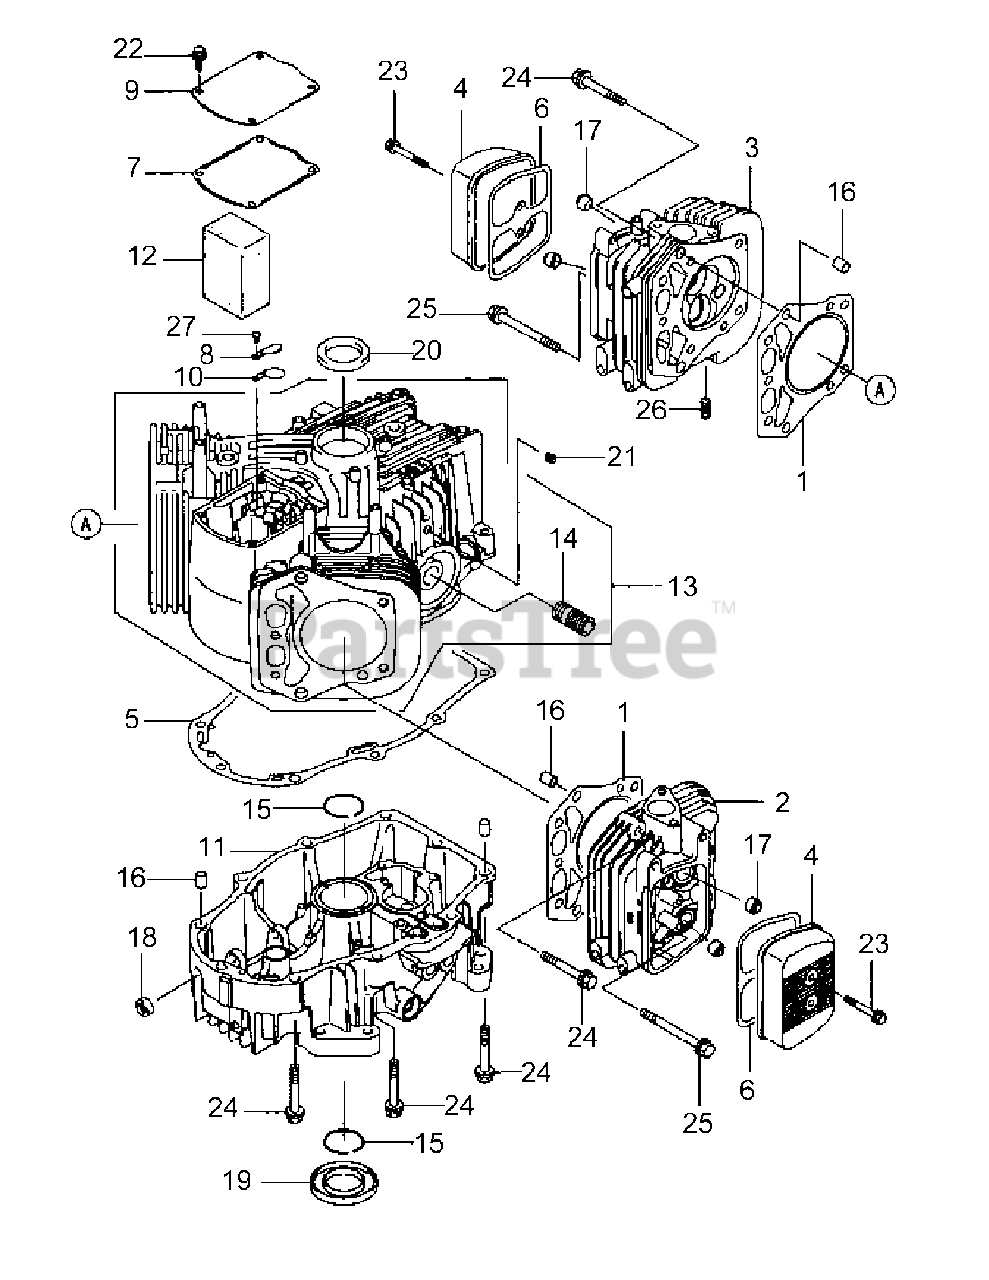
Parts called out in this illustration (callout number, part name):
2	HEAD-COMP-CYLINDER, #2
3	HEAD-COMP-CYLINDER, #1
4	CASE-ROCKER
6	GASKET, ROCKER CASE
7	GASKET, BREATHER
11	COVER-CRANKCASE
12	BREATHER ELEMENT
13	CRANKCASE-COMP
17	SEAL-OIL,RVC2 6X11X10.2
18	SEAL-OIL,SO 8X14X5 HS
19	SEAL-OIL,SD 35X62X8 L HS
20	SEAL-OIL, SD 35X48X8 R HS
22	BOLT-FLANGED
23	BOLT-FLANGED
24	BOLT-FLANGED
25	BOLT-FLANGED
